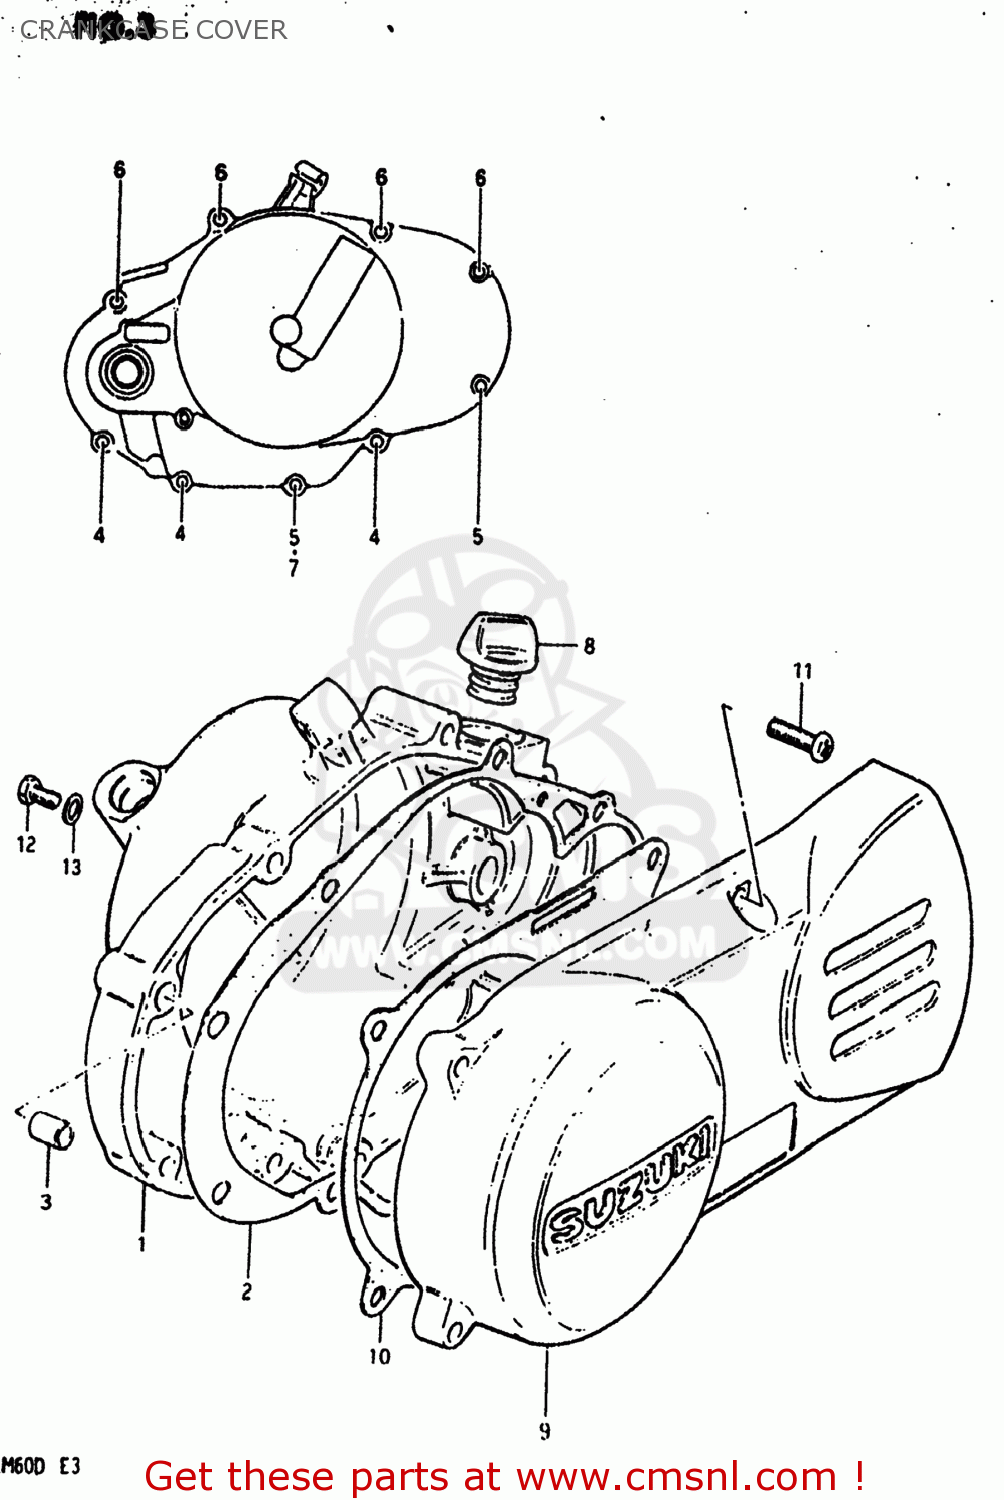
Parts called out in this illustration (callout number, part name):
1	COVER,CLUTCH
2	GASKET,CLUTCH COVER (MCA)
3	PIN
4	SCREW
5	SCREW
6	SCREW
7	GASKET(6.2X11X1).2 (NAS)
8	PLUG
9	COVER,MAGNETO
10	GASKET,MAGNETO COVER (NAS)
11	SCREW 6X85
12	SCREW(6X10)
13	GASKET(6.2X11X1) (NAS)
